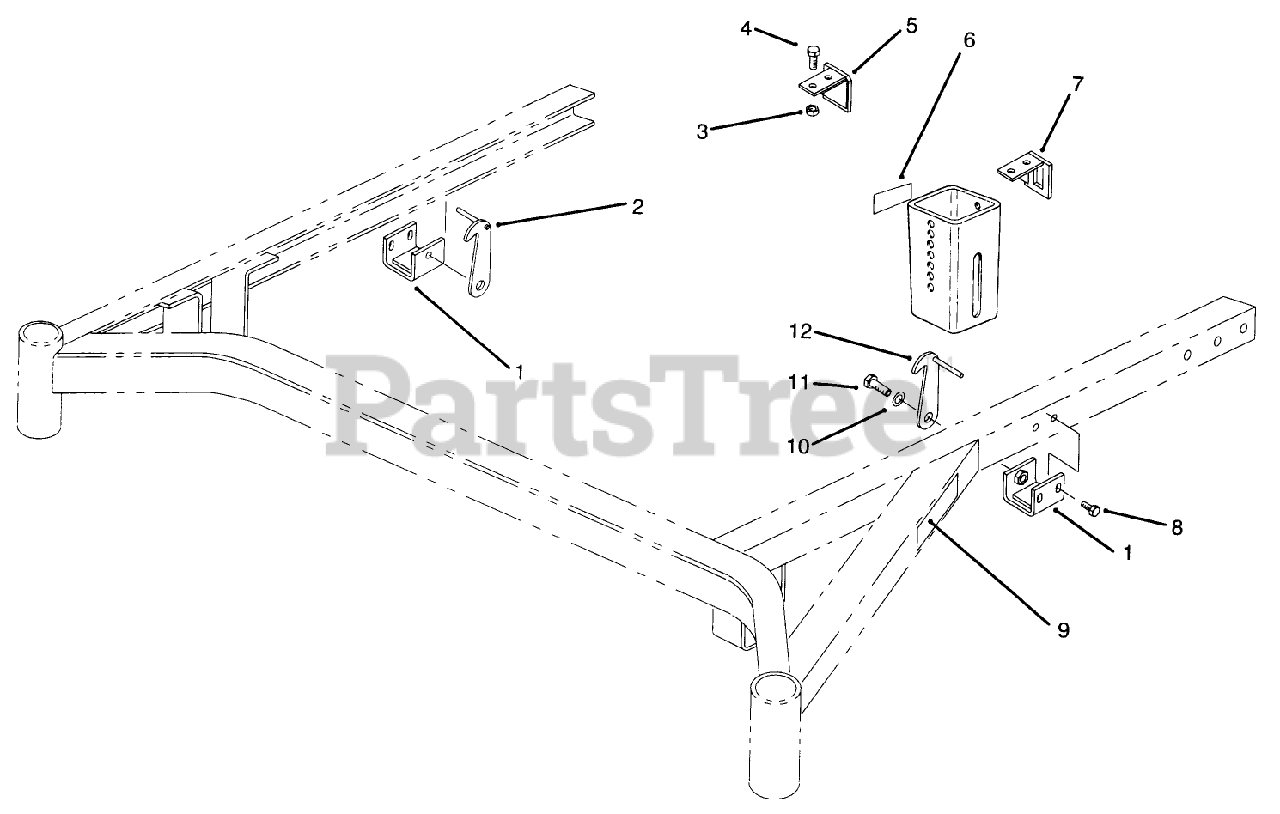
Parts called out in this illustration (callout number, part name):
1	BRACKET WA - LATCH R
2	Retainer-Deck, RH
3	NUT-LOCK, SIDE
4	SCREW-HH
5	Bracket-Deck, RH
6	DECAL-WARNING
7	Bracket-Deck, LH
8	SCREW-HWH
9	DECAL-HOC
10	WASHER-SPRING
11	SCREW-HH
12	Retainer-Deck, LH
